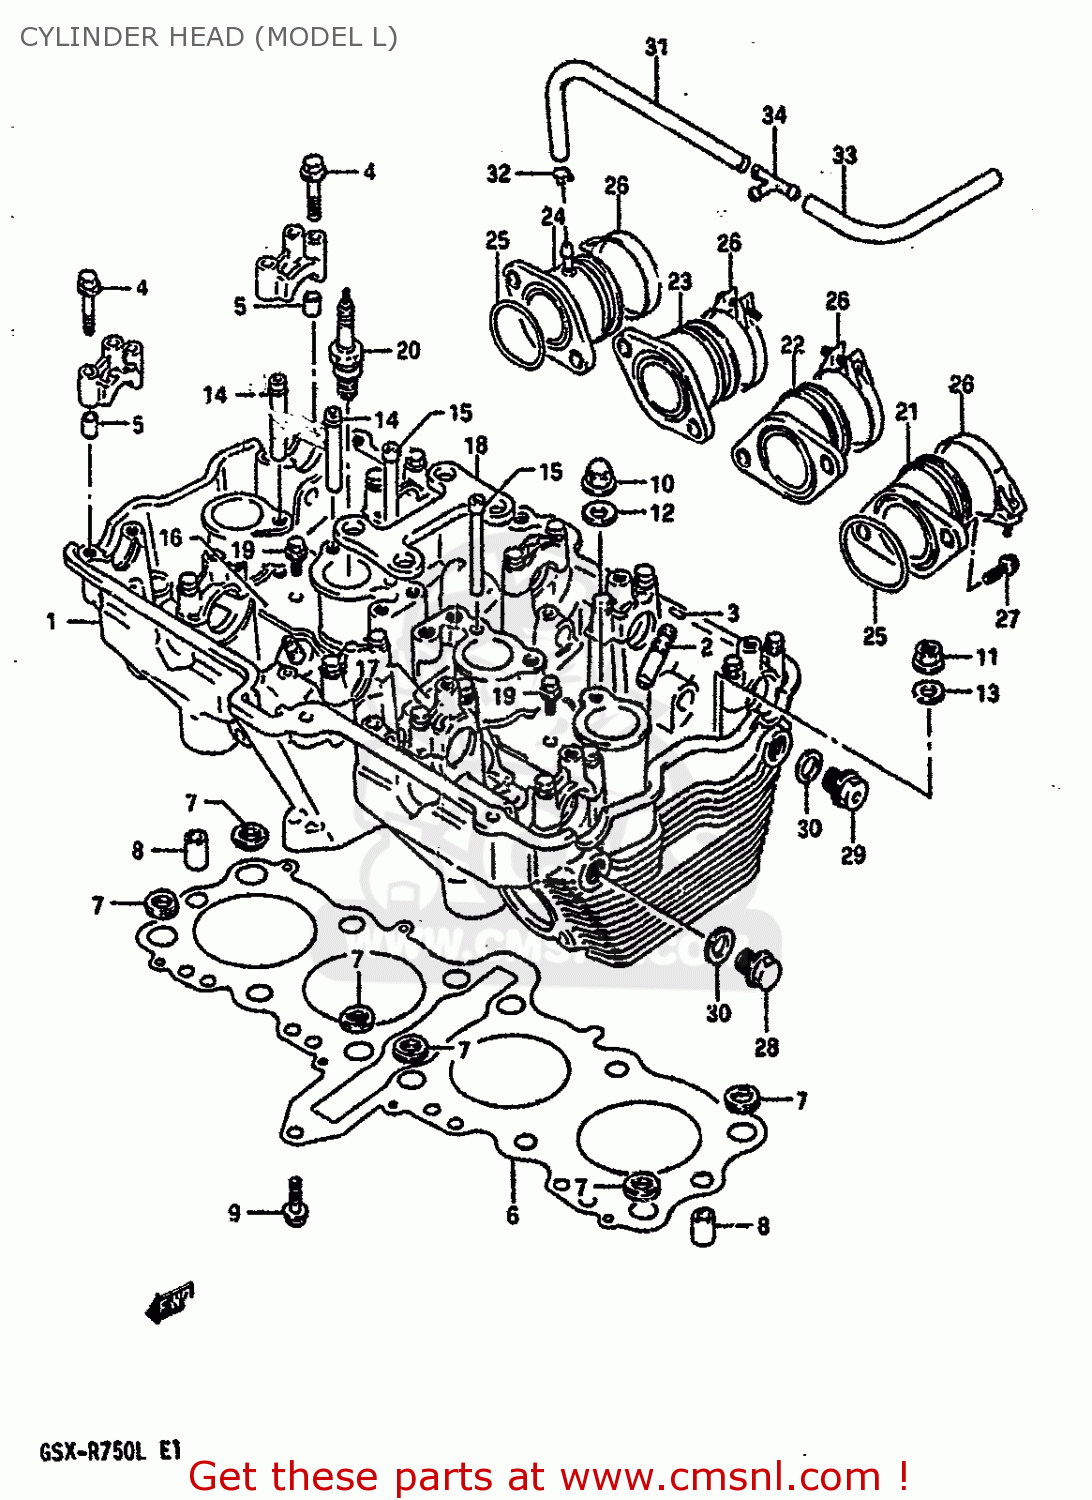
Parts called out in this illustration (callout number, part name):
1	HEAD ASSEMBLY,CYLINDER
2	GUIDE,VALVE
3	RING,SNAP
4	BOLT(6X39)
5	PIN(6.2X8X11)
6	GASKET,CYLINDER HEAD
7	O RING,HEAD GASKET
8	PIN
9	BOLT 6X30
10	NUT
11	NUT
12	GASKET(10.2X20X2).3 (NAS)
13	WASHER (10.5X22X2.3)
14	PIPE,OIL NO.1
15	PIPE,OIL NO.3
16	PLATE,OIL PIPE,R
17	PLATE,OIL PIPE,L
18	PLATE,HEAD REINF
19	BOLT
20	PLUG,SPARK(CR9EK)
21	PIPE,INTAKE
22	PIPE,INTAKE
23	NET,INTAKE
24	PIPE,INTAKE
25	O RING(D:2.4,ID:41.7)
26	CLAMP
27	SCREW
28	PLUG
29	PLUG
30	GASKET(14X19.2X2) (NAS)
31	HOSE
32	CLIP
33	HOSE
34	JOINT,3 WAY
